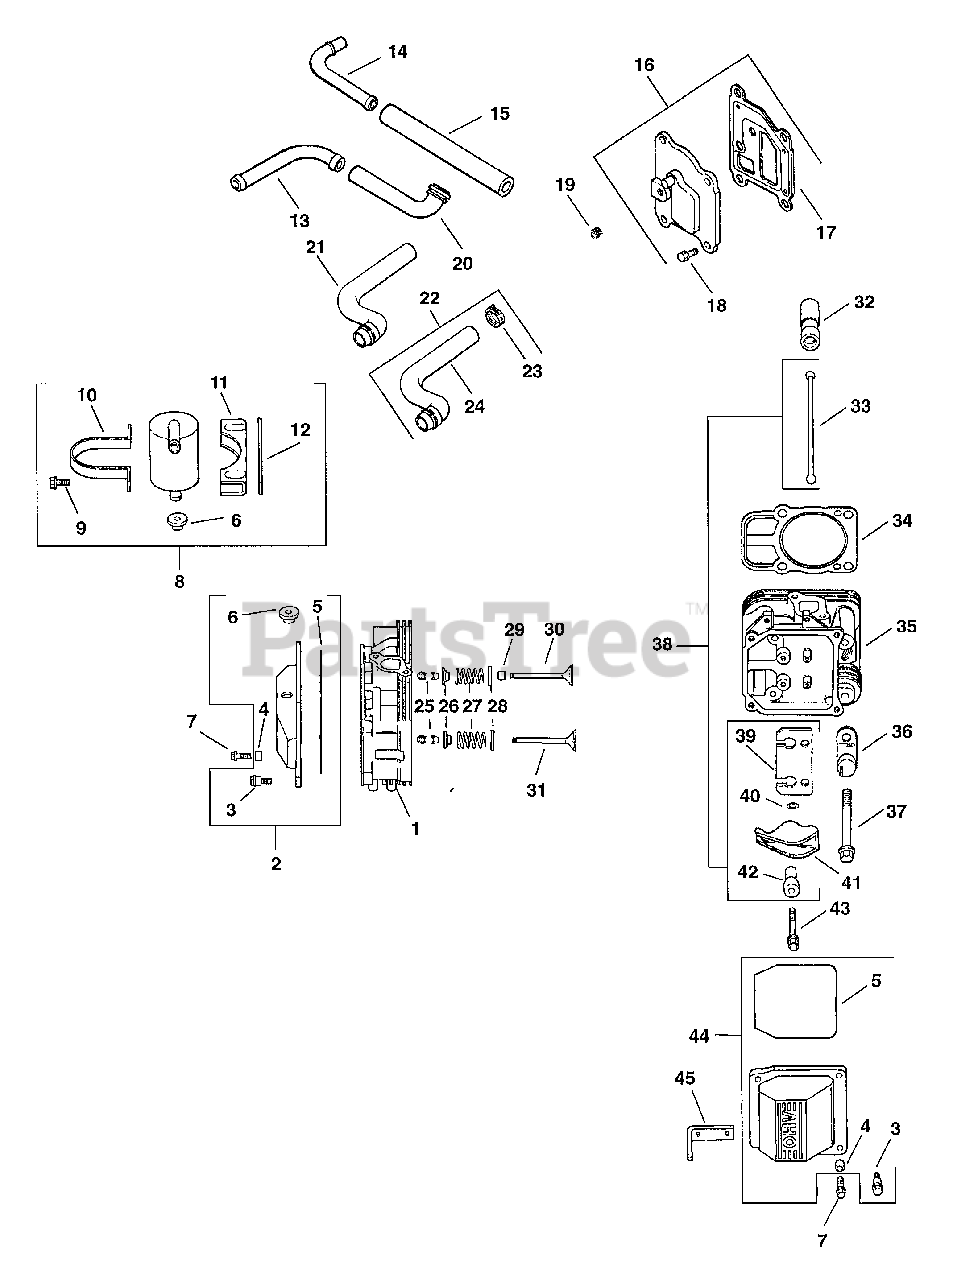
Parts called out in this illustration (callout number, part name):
2	VALVE COVER KIT-USE 24 755 142-S
3	SCREW, SHOULDER
5	O-RING - USE 24 153 16
7	SCREW - USE M-651030
8	KIT, BREATHR SEPARATR-(#24755241S)
9	SCREW - USE M-545016
9	SCREW - USE M-449020
10	STRAP, BREATHER - USE 24 755 241-S
11	BRACKET, BREATHER SEPARATOR
12	SPACER
15	HOSE, BREATHER (WAWB)-USE 24 326 63-S
16	KIT, BREATHER COVER W/GASKET
18	SCREW - USE M-645020
25	KIT, RETAINER
26	RETAINER, VALVE SPRING - USE 25 173 28-S
27	SPRING, VALVE
28	RETAINER, SPRING
30	VALVE, INTAKE (STD)
30	VALVE, INTAKE (.25)
31	VALVE, EXHAUST (STD) - USE 32 016 01-S
31	VALVE, EXHAUST (.25)
32	LIFTER - USE 12 351 02
33	KIT - USE 24 755 66
37	SCREW - USE 62 086 08-S
38	KIT - USE 24 755 66
39	KIT - USE 24 755 66
41	ROCKER ARM - SEE PARTS BULLETINS 182 FOR TWINS AND 200 FOR SINGLES
42	KIT - USE 24 755 66
43	Screw, hex. flange M6x1.0x34
44	ROCKER COVER KIT-USE 24 755 141-S
45	STRAP, LIFTING-USE 25 445 03-S
